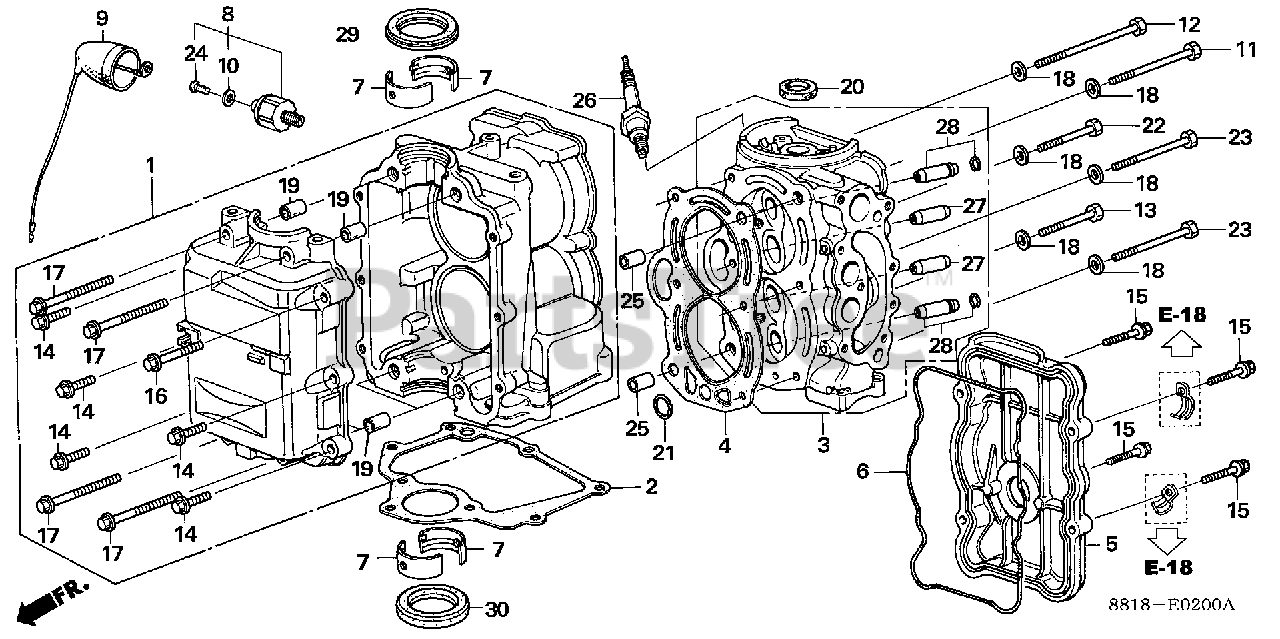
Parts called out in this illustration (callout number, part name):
1	CYLINDER ASSY. *NH8* (DARK GRAY)
2	GASKET, OIL PAN
3	CYLINDER HEAD *NH8* (DARK GRAY)
4	GASKET, CYLINDER HEAD
5	COVER, CYLINDER HEAD *NH8* (DARK GRAY)
6	GASKET, HEAD COVER
7	BEARING, CRANKSHAFT
8	SWITCH, OIL PRESSURE
9	WIRE, OIL PRESSURE SWITCH
10	WASHER (4MM)
11	BOLT, HEAD (8X70)
12	BOLT, HEAD (8X94)
13	BOLT, HEX. (8X55)
14	BOLT, FLANGE (6X25)
15	BOLT, FLANGE (6X28)
16	BOLT, FLANGE (6X35)
17	BOLT, FLANGE (8X45)
18	WASHER, HEAD (8MM)
19	PIN, DOWEL (10X12)
20	OIL SEAL (16X28X6)
21	O-RING (10.8X2.4) (ARAI)
22	BOLT, HEX. (8X50)
23	BOLT, HEX. (8X65)
24	SCREW, PAN (4X6)
25	PIN, DOWEL (10X16)
26	SPARK PLUG (DR-4HS) (NGK)
26	SPARK PLUG (DR-5HS) (NGK)
26	SPARK PLUG (X16FSR-U) (DENSO)
27	GUIDE, VALVE (OVER SIZE)
28	GUIDE, EX. VALVE (OVER SIZE)
29	OIL SEAL A (30X42X7)
30	OIL SEAL B (30X42X7)
